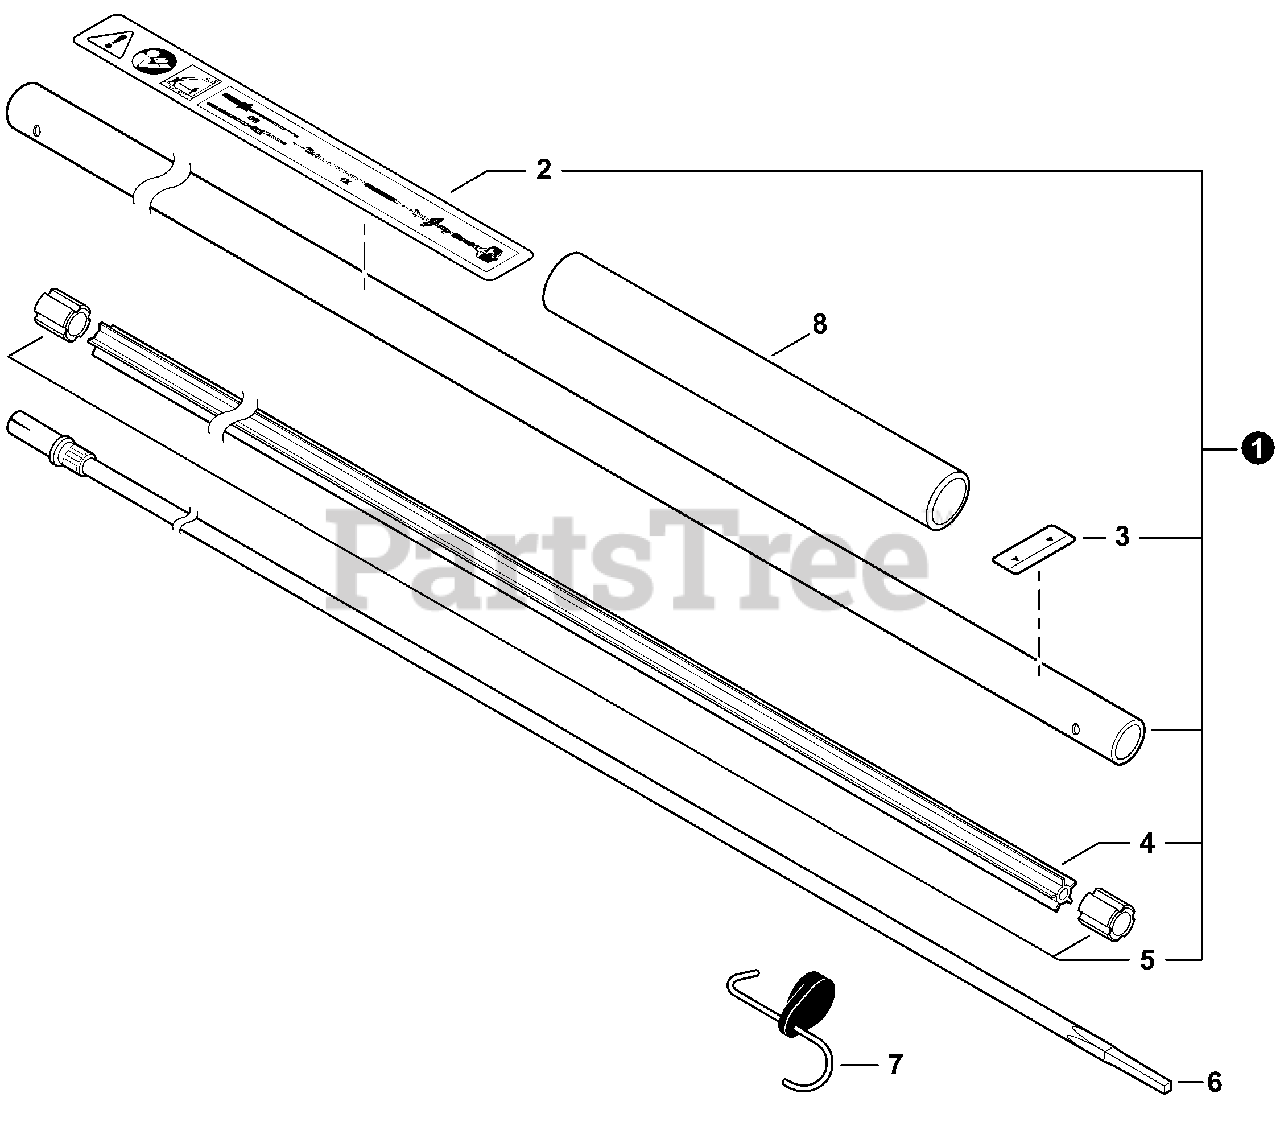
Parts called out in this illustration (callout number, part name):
1	MAIN PIPE ASSY
2	LABEL, CAUTION
3	LABEL - ALIGNMENT
4	LINER - FLEXIBLE
6	DRIVESHAFT - FLEXIBLE
7	HANGER, ATTACHMENT
8	GRIP, HANDLE
